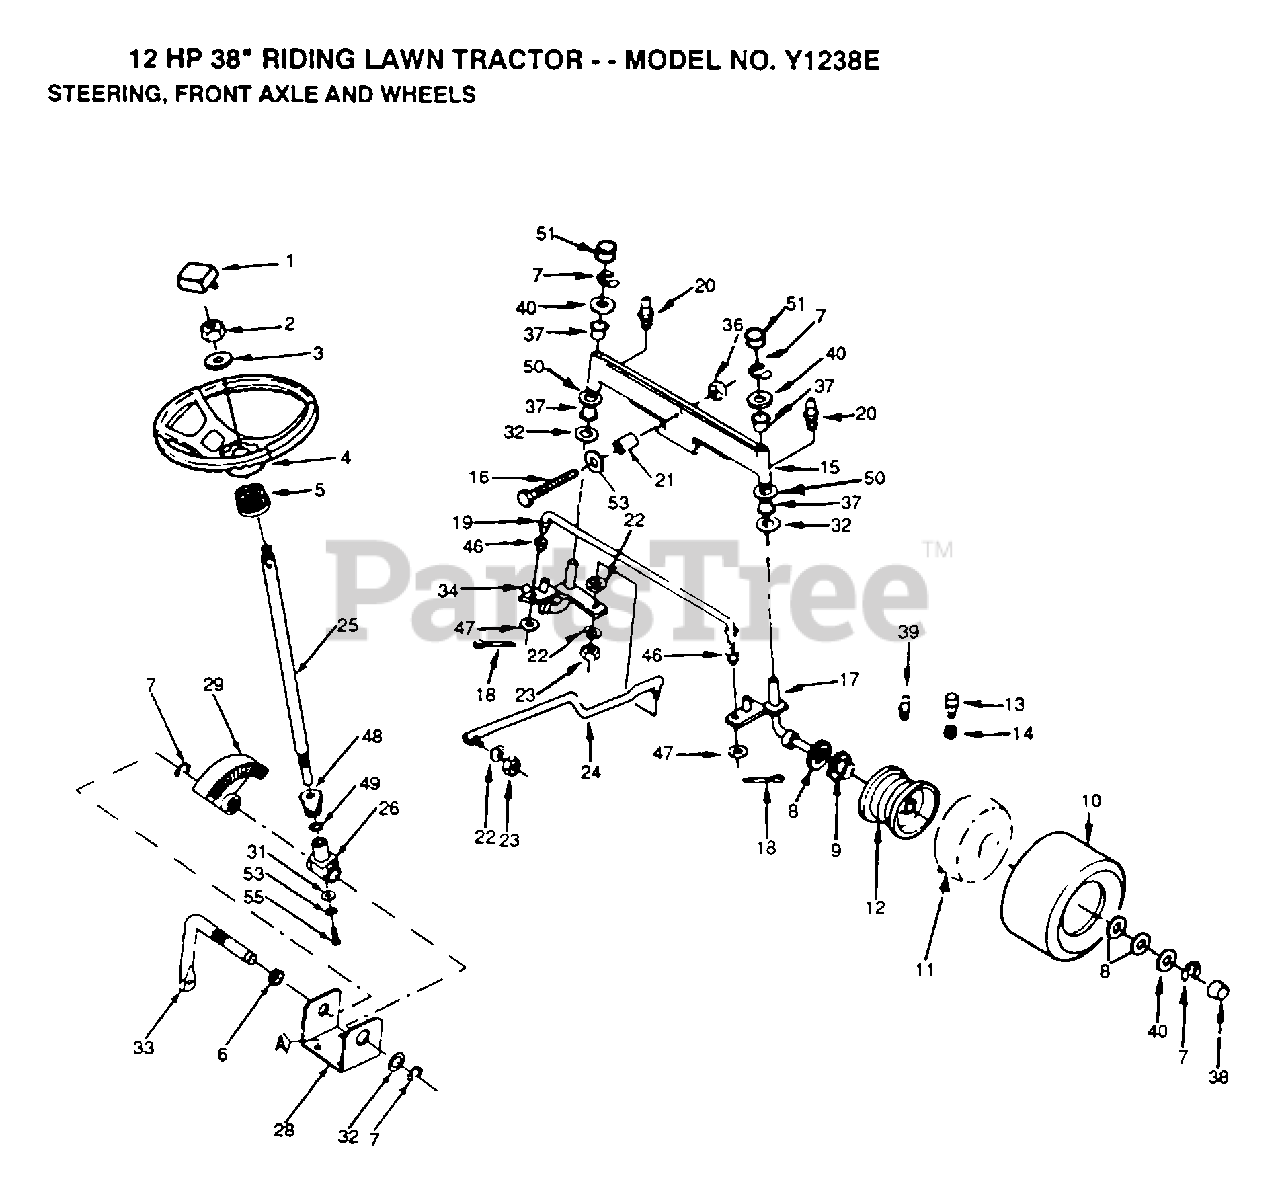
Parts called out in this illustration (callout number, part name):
1	INSERT STEERING
3	WASHER
6	NYLINER T
7	RING
8	WASHER
9	"FLANGE, BEARING"
11	TUBE.5.3/4.5/6
13	VALVE STEM LT
14	VALVE CAP
16	BOLT LT
18	COTTER PIN
20	ZERK M
21	BEARING
22	LOCKWASHER
26	SUPPORT.SHAFT
28	"BRKT,STEERING"
32	WASHER .T
34	SPINDLE-LH LT
37	COL. SRTG. BEAR.
38	HUB CAP
39	FITTING LT
40	WASHER
47	WASHER
48	"GEAR,PINION"
49	THRUST WASHER
50	WASHER
51	CAP
55	"SCREW,SPECIAL"
